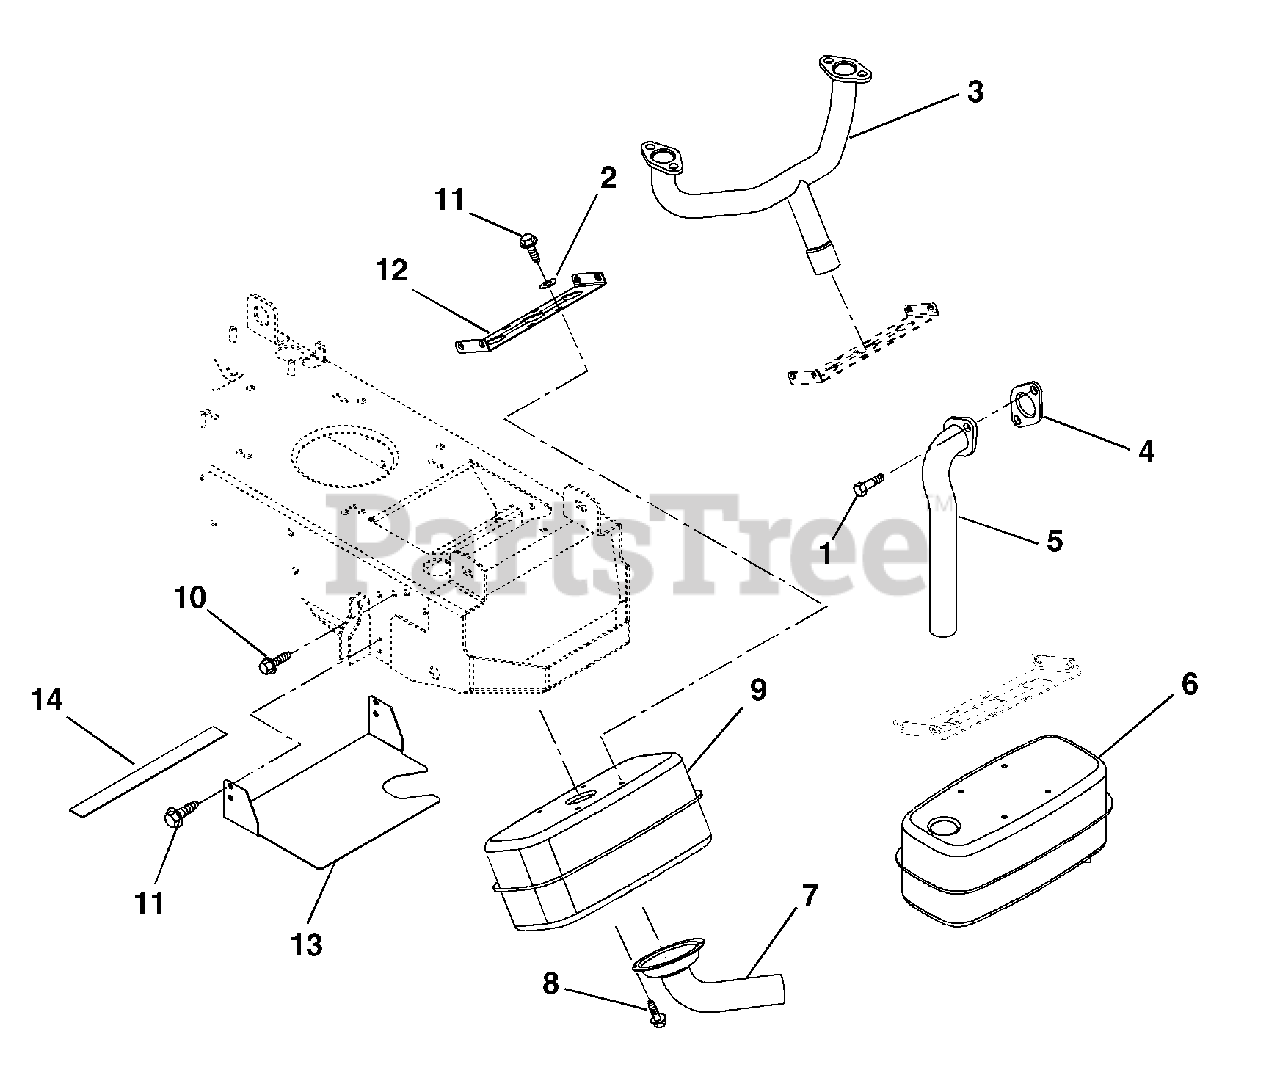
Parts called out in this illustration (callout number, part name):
1	SCR-CAP .31-18X.75 S/HD
2	@WSHR-FL-STL.250X.56X.049 YWZC
3	PIPE, EXHAUST INTEK V TWIN
4	GASKET B&S#272293
5	PIPE - EXHAUST
6	MUFFLER W/DEFLECTOR
7	DEFLECTOR - EXHAUST
8	SCR-TAP 8-32X.38 SL HWH YWZC
9	MUFFLER - EXHAUST
10	@SCR-TAP .31-18X.50 HWH TR YWZ
11	@SCR-TAP 12-24X.75 HWH YWZC
12	BRACKET - MUFFLER
13	SHIELD, HEAT
14	HEAT SHIELD- FABRIC 1X10.75
